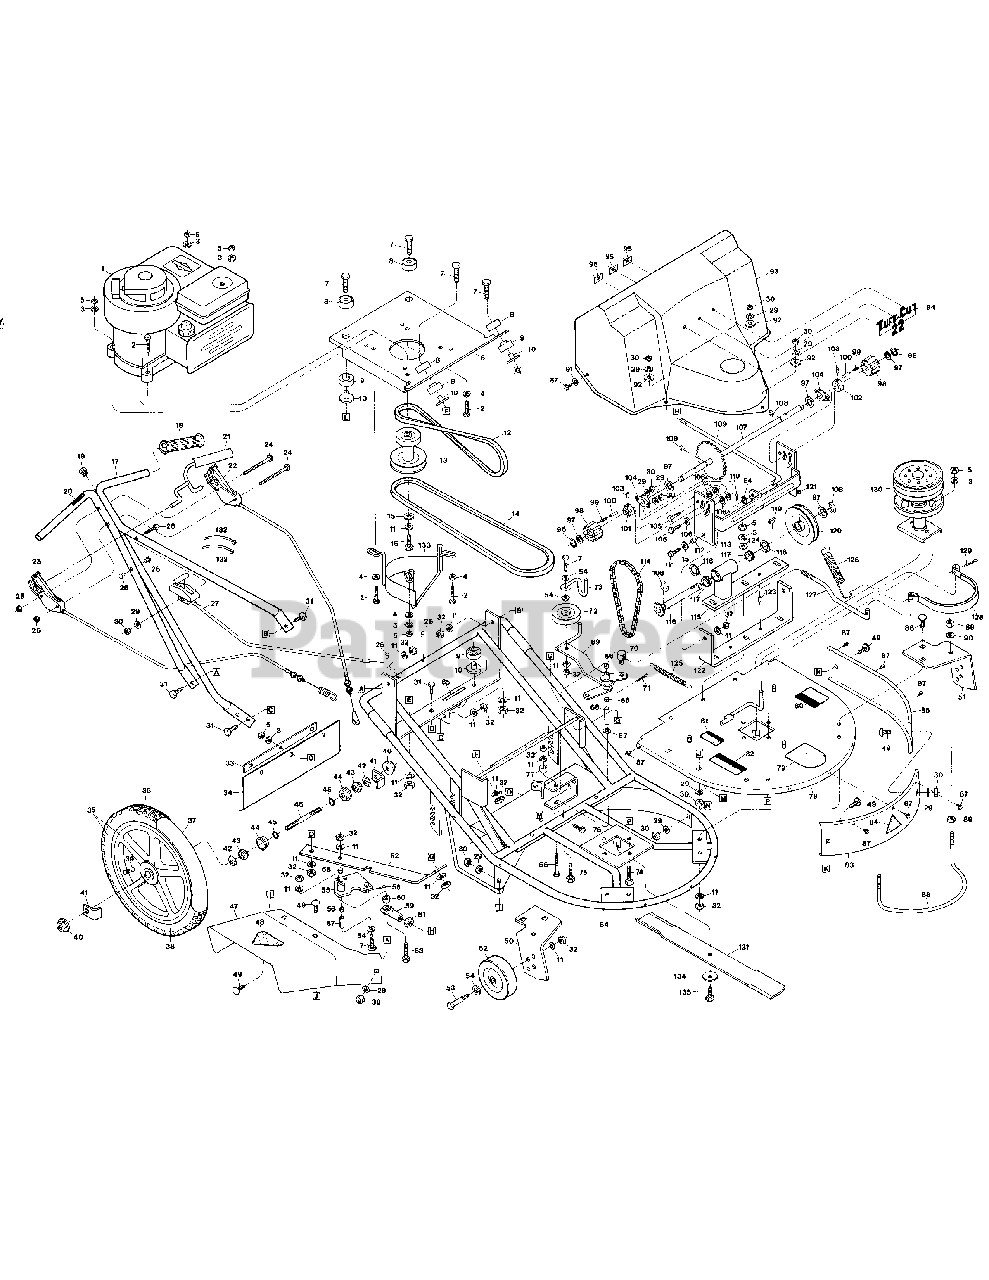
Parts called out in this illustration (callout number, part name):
2	SCR-HH 5/16-18X1.75
3	WASHER-LK .312
4	WASHER-.88X312X.08
5	NUT-HEX 5/16-18
6	BASE-ENGINE
7	SCR-HH 3/8-16X2.0 G5
8	REBOUND MOUNT-24"
9	LOAD CARRYING MOUNT-24"
10	TUB-SPACER 24"
11	WASHER-LK .375
12	TRACTION-V BELT
13	PULLEY-ENGINE
14	BLADE-V BELT
15	WASHER-1.0X.438X.104
16	SCR-HH 3/8-24X1.25 GR5
17	ASSM-HANDLEBAR 22" PUSH (INCL. 18 & 20)
18	GRIP-HANDLEBAR
19	PLUG-METAL CAP
20	DECAL-STARTING INST
21	BAIL WELDMENT-SELF PROP
22	CABLE-WHEEL DRIVE (CABLE & LATCH)
23	CABLE-BLADE DRIVE (CABLE & LATCH)
24	SCR-PHP M10-24X4.0
25	NUT-HEX LOCK #10-24 PL
26	PLUG-HOLE (RECOIL START ENGINES ONLY)
27	SPEED CONTROL-ENGINE (CABLE & CONTROL)
28	SCR 1/4-20X1.5 PL CSHH
29	WASHER-LK .25
30	NUT-HEX 1/4-20
31	SCR-HH 3/8-16X.75 G5
32	NUT-HEX 3/8-16
33	BRKT-PROT TRAILER PNT
34	TRAILER-MOWER
35	ASSM-TIRE & WHEEL (INCL. 36-40, 42-46)
36	TIRE-16 X 2.125
37	TUBE-16"
38	ASSM-16" RIM
39	CAP-VALVE
40	NUT-HF/LK 3/8-24 WHIZ
41	TAB-WHEEL LOCK 22"
42	NUT-LOCK 3/8-24 PL
43	NUT-ACORN 3/8-24
45	BEARING-WHEEL
46	AXLE-WHEEL
47	CHUTE-DISCHARGE W/DECAL
48	DECAL-BLADE WARNING
49	SCR-CARR 1/4-20X.375
50	HANGER-RT WHL PNT
51	HANGER-LT WHL PNT
52	ASSM-TIRE&WHEEL 6X1.50
53	SCR-SHLDR 3/8-16X1.406
54	WASHER-FLAT 3/8 SAE
55	ASSM-BELLCRANK W/BUSHING (INCL. TWO BEARINGS REF. NO. 56)
56	BEARING-SLEEVE
57	TUBE-BELL CRANK
58	PIN-COTTER .09X.75
59	JOINT-BALL
61	NUT-HEX/JAM 3/8-24
62	STRAP-BELLCRANK
63	SCR-HH 3/8-16X1.75 GR5
64	WELDMENT-FRAME 22" (INCL. REF. NO. 65)
65	DECAL-CPSC COMPLIANCE
66	SCR-HH 3/8-16X4.5 G5
67	SHIM-WASHER
68	TUBE-PIVOT
69	ARM-IDLER W/BUSHINGS (INCL. TWO BEARINGS REF. NO. 56)
70	TRUNNION
71	PIN-COTTER .094X1.0
72	PULLEY-IDLER
73	GUIDE-BLADE BELT
74	SCR-HH 5/16-18X1.0 G5
75	BOLT-HH 5/16-18 X 2 G5
76	SCR-HHC 5/16-18X.75 GR 5
77	SPACER-.625X.387X1.0
78	ASSM-DECK TOP 22" (INCL. 79-82)
79	DECAL-TUFFCUT LOGO
80	DECAL-WARNING PROCEDURES
81	DECAL-CAUTION BELT COVER
82	DECAL-DANGER GUARD
83	WRAP-FRONT 22" PNT (INCL. 84)
85	WRAP-LH PNT
86	SCR-CARR 3/8-16X1.00
87	SCR-HW M10-16X.75 SELT DR
88	BUMPER-22" PNT
89	NUT-HEX JAM 1/2-13
90	WASHER-LK .5
91	WASHER-#10 TYPE B PLN
92	WASHER-FLAT 1/4 SAE
93	KIT-SVC 22" BELT COVER
94	PLATE-NAME 22"
95	CLIP, NAMEPLATE MOUNTING
96	RING-HEAVY EXT .575 ID
97	WASHER-1.0X.632X.03
98	ROLLER-DRIVE
99	SPRING-DOWEL RETURN
100	PIN-DOWEL 1/4"
101	RATCHET-RH MACH
102	RATCHET-LH MACH
103	PIN-ROLL 3/16 X 1.5
105	SCR-HH 1/4-20X.75 G5
106	WASHER-FLAT 1/4 SAE
106A	WASHER-FLAT 1/4 SAE (SAME AS REF. NO.106 USED FOR SHIMMING, AS REQUIRED)
107	WELD-AXLE 22" DRIVE SHAFT
108	RING-RETAINING "E"
109	ROD-WHEEL DR LINK 22"
110	CLIP-HITCH PIN #13 PL
111	SCR-HH 3/8-16X1.0 G5
112	SPACER-.390X.630X.281
113	ASSM-TRACTION BRKT
114	CHAIN #35-46 PITCHES
115	BRKT-JACKSFT MTG PNT
116	JACKSFT-WELD HEAT TREAT
117	BEARING
118	RING-RETAINING EXTERNAL
119	KEY-HI PRO 1/8X1/2
120	PULLEY-WHEEL DRIVE
121	SCR-SET 1/4-20X1/4
122	BRKT-U CHANNEL PNT
123	PIN-ROLL 1/4X1/2
124	WASHER
125	SPRING-WHEEL OR RETURN
126	SPRING-SPINDLE BRAKE
127	ROD-BRAKE ENGAGEMENT
128	BRAKE BAND & LINING
129	PIN-COTTER .125X.750
130	KIT-SPINDLE TUFFCUT I&II
131	BLADE-22" TUFFCUT NLA ETION
132	TIE-RED
133	GUIDE-BELT PNT
134	WASHER-BELLEVILLE 3/8
135	SCR-HH 3/8-24 X 1.5" G8
